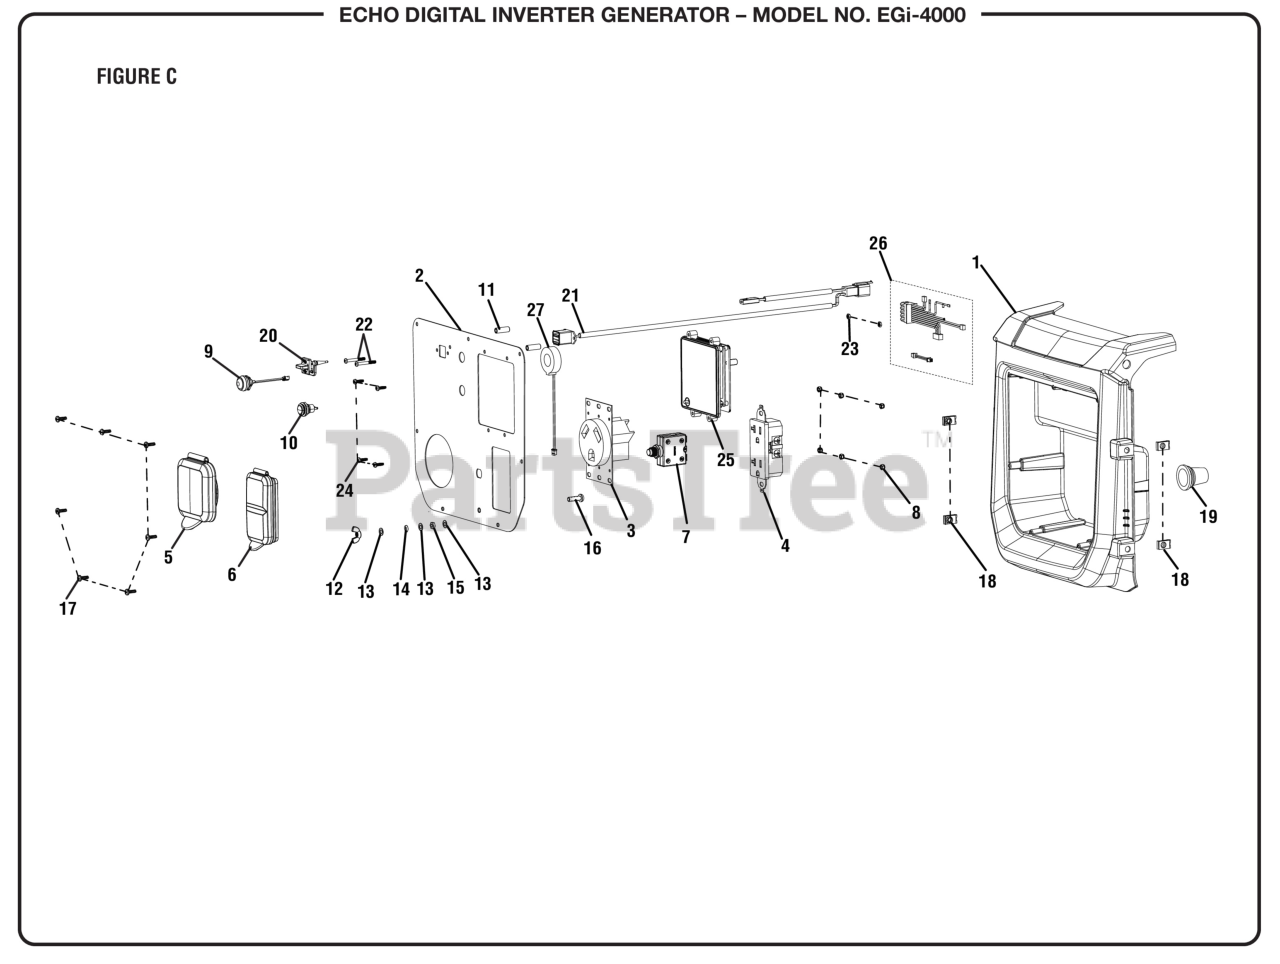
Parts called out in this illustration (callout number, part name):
1	HOUSING, ELECTRICAL PANEL
2	PANAL, CONTROL
3	TRANSFORMER, CURRENT TYPE-A
4	OUTLET, 120V (20 AMP)
5	COVER, OUTLET
6	COVER, 120V OUTLET
7	BREAKER, 20A
8	NUT, M4 LOCK NUT
9	SWITCH, AUTO IDLE
10	SWITCH, RESET W/O WIRES
12	NUT, WING
14	WASHER, LOCK
15	NUT, HEX
19	BOOT, WIRING RUBBER
20	COVER, DUAL USB
21	HARNESS, USB WIRE
25	ASSY., ECHO COMMAND
26	WIRE HARNESS, LCD
27	TRANSFORMER, CURRENT TYPE-A
